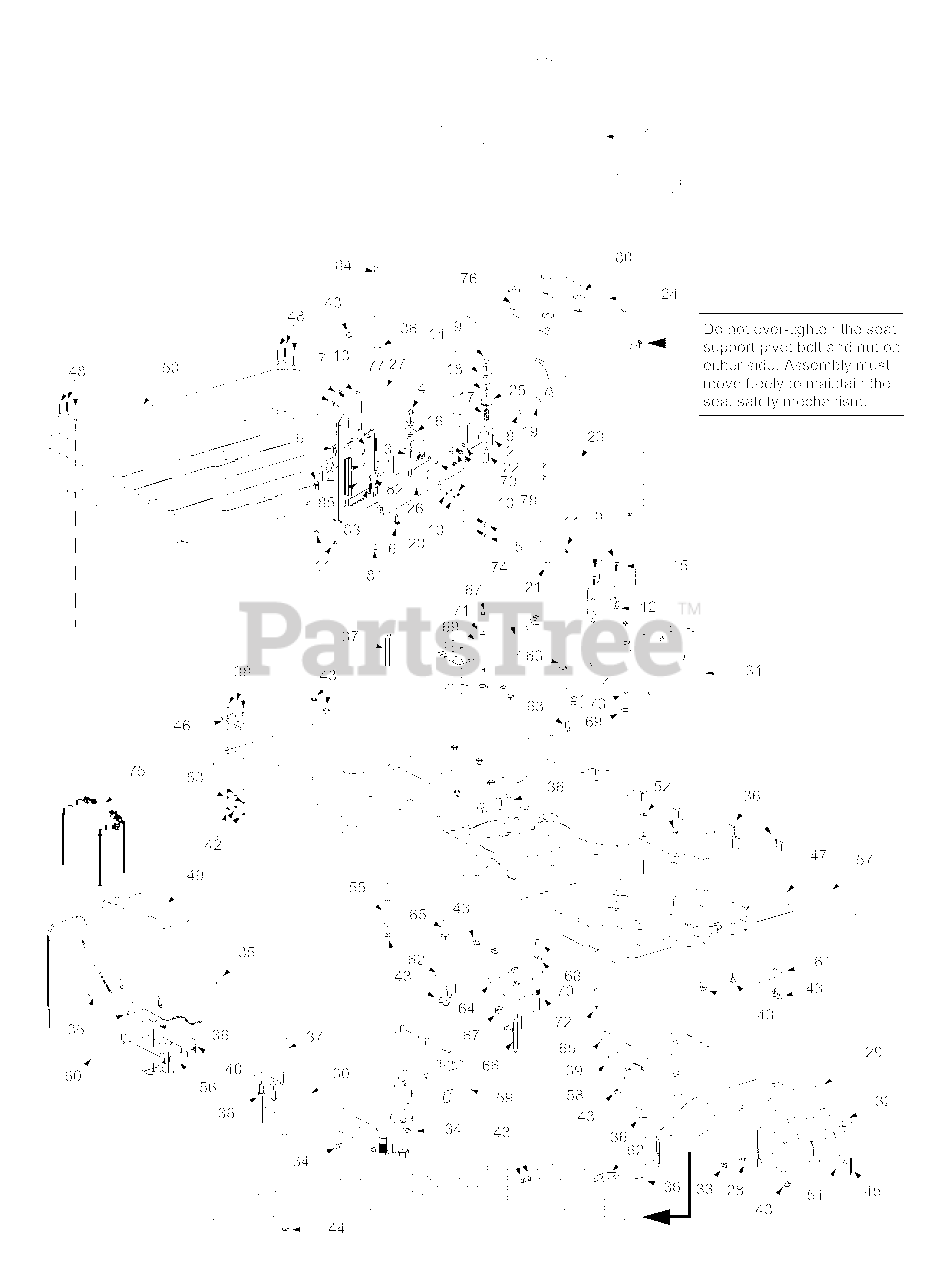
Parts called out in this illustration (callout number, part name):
1	Seat: Black, Low Back
5	Carriage Bolt 5/16 x 1.5"
6	Hex Bolt M8-1.25: 20
7	Special Screw M6-1: 16
8	Hex Bolt M8-1.25: 45
9	Flange Lock Nut 3/8-16
10	Hex Nut M6-1
11	Hex Lock Nut M8-1.25
12	Flange Lock Nut 5/16-18
13	Ratchet Clip
14	Compression Spring
15	Engine Heat Deflector
16	Compression Spring
17	Compression Spring
18	Bell Washer .375 x .870 x .063
19	Shoulder Bushing
20	Lock Washer
21	Flat Washer 8.4 x 35
22	Shoulder Screw
26	Bag Switch Cover
27	Seat Support Bracket
28	Switch Plate
34	TT Screw 1/4-20 x 0.5"
35	Machine Screw
36	Hex Screw M8-1.25: 20
37	Special Screw
38	Special Screw
39	Clevis Pin
40	Speed Nut 1/4-20
42	Hex Nut
43	Hex Lock Nut
44	Flange Lock Nut
45	Cotter Pin
46	Tray Hinge
47	Foot Pad
49	Battery Cover
50	Bag Tray
51	Flat Washer .64 x 1.24 x .06
52	Flat Washer 8.4 x 16
53	Lock Washer M4
55	Spacer
62	Cable Bracket
63	TT Sems Screw 3/8-16 x 1.0
64	Belt Keeper Bracket
65	Hex Bolt M8-1.25: 30
66	Pin: Belt Guard
67	Lock Nut M8-1.25
68	Hex Nut 5/16-18
69	Engine Mount: Gromm.
70	Lock Washer 5/16
71	Flat Washer 8.4 x 24
72	Belt Keeper Rod
73	Spacer
76	Self-Tapping Screw 3/8-16 x 1.250
77	Self-Tapping Screw 1/4-20 x 0.75
78	Lock Washer
79	Hex Sems Nut 1/4-20
80	Spacer
81	Speed Nut
82	Bag Hinge Bracket
83	Torsion Spring
84	Hinge Pin
85	Bag Chute Door Assembly
